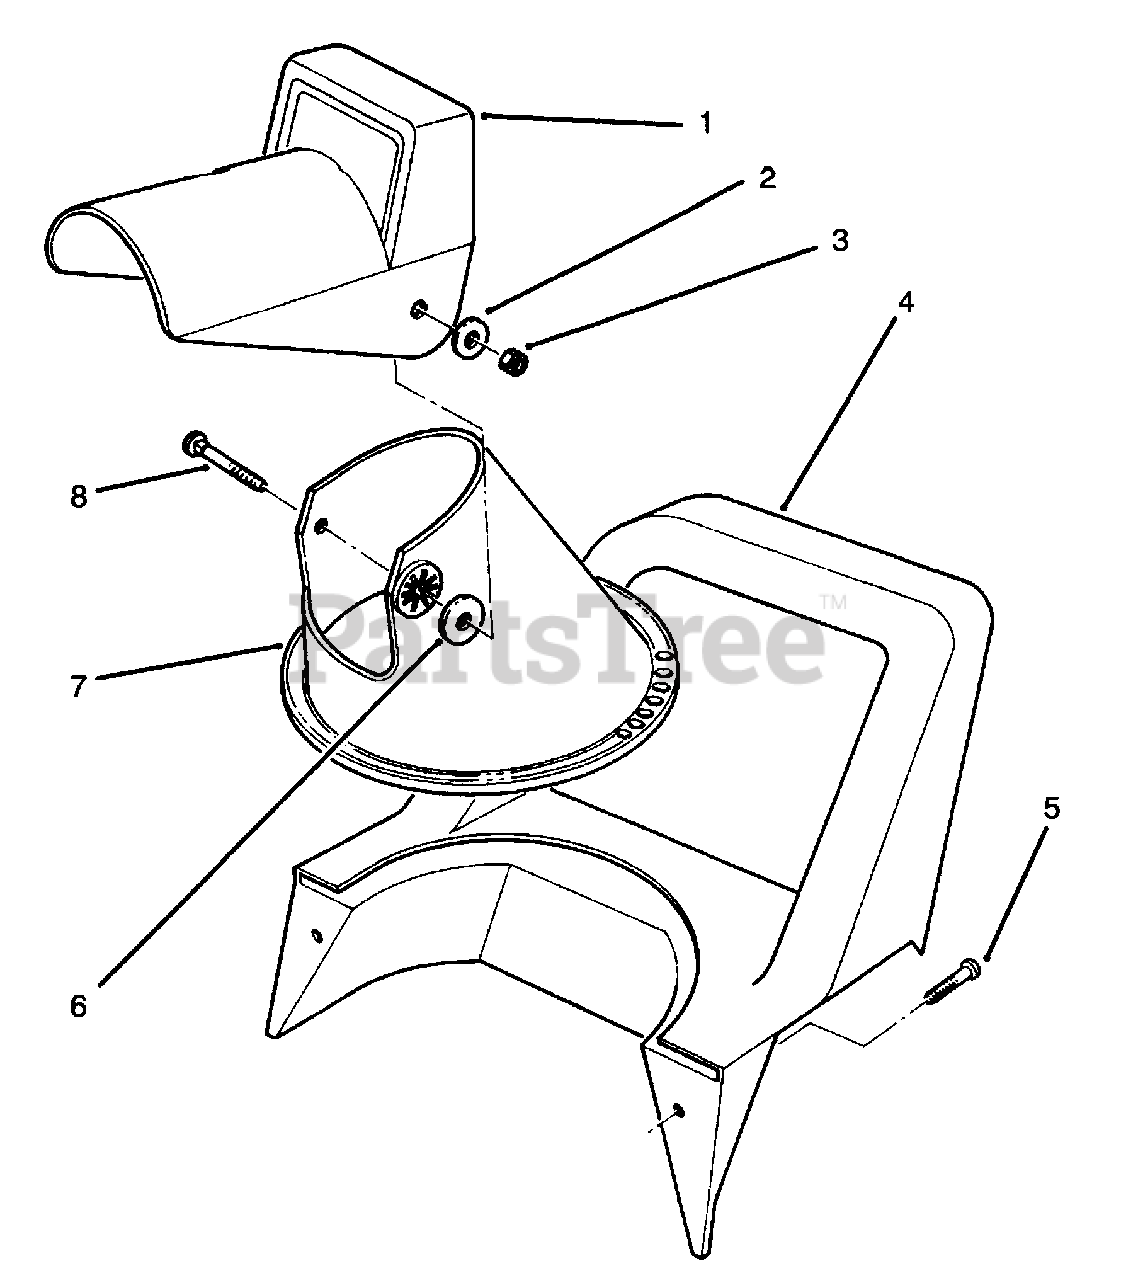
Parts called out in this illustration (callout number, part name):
1	Chute-Deflector
2	Washer-Flat
3	Nut-Lock
4	Handle-Middle
5	Screw-Pan Hd. Form
6	Washer-Rubber
7	Chute-Lower
8	Bolt-Carriage
